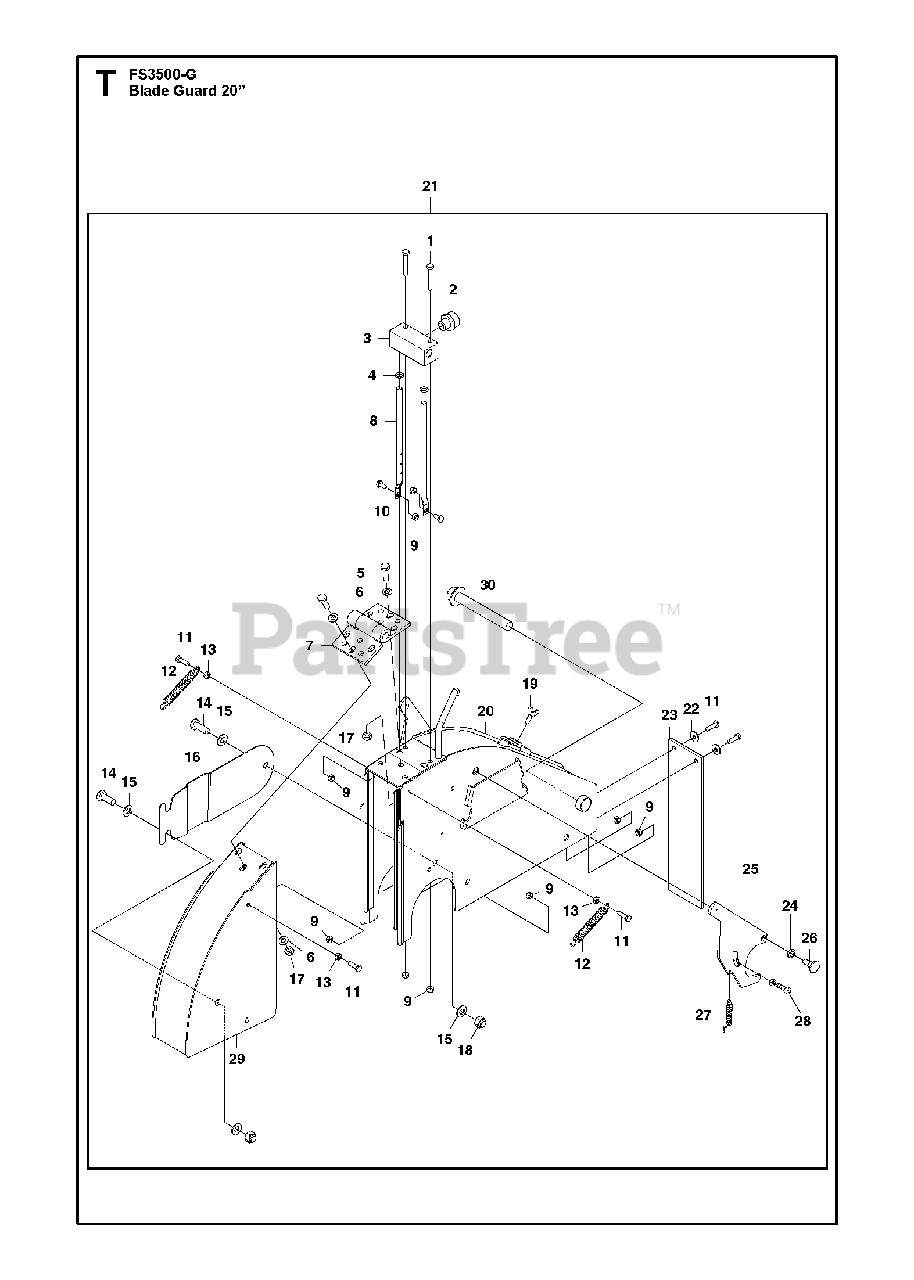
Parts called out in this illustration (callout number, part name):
6	WASHER
9	HEXAGON LOCKING NUT
15	WASHER
17	HEXAGON LOCKING NUT
18	HEXAGON LOCKING NUT
